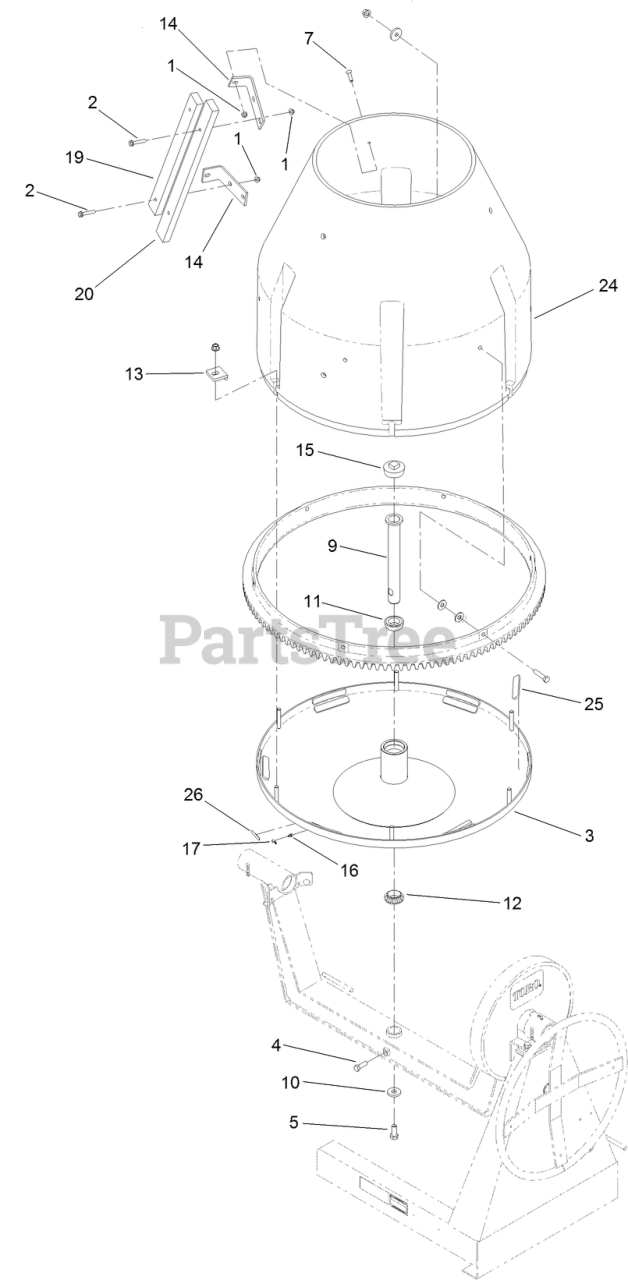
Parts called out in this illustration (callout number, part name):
1	NUT-HF, NI
2	SCREW-HHF
4	SCREW-HH
5	SCREW-HH
7	SCREW-FH, HEX SOCKET
9	SPINDLE
10	WASHER-FLAT
11	BEARING
12	BEARING-ROLLER
13	CLAMP-DRUM
14	BRACKET-PADDLE
16	FITTING
17	CAP-PLUG
19	PADDLE
20	PADDLE
24	DRUM ASM
25	PAD-RUBBER
26	DECAL-GREASE
